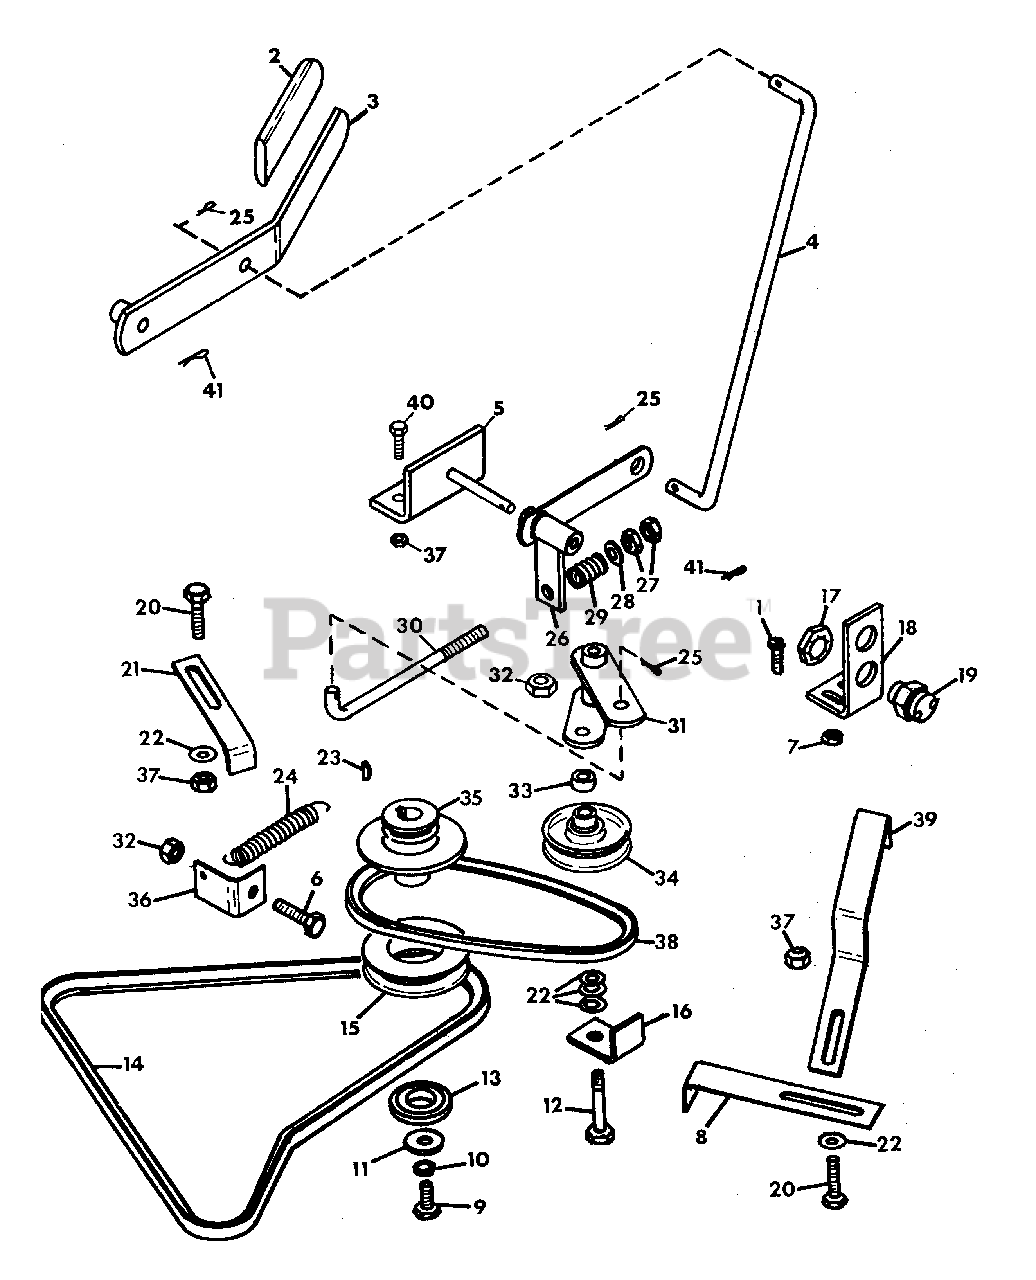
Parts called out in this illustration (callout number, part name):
1	Screw, Mach. 10-24x1.50
2	Grip, PTO Lever
3	Weldment, PTO Control Handle
4	Rod, PTO Control
5	Weldment, PTO Hand Lever Brkt.
6	Bolt, Hex 3/8-16x1.00
7	Nut, Lock 10-24
8	Belt Guide, Rear Clutch Hub
9	Bolt, Hex 7/16-20x2.00
10	Washer, Lock 7/16
11	Washer, Special Flat
12	Bolt, Hex 3/8-16x2.25
13	Bearing, Ball 1.574x3.149x.708
14	Belt, Mower
15	Sheave, Mower Clutch
16	Belt Guide, PTO Idler
17	Nut, Stamped 9/16-18
18	Bracket, Interlock Switch
19	Switch, Interlock
20	Bolt, Hex 5/16-18xl.75
21	Belt Guide, Front Clutch Hub
22	Washer, Flat .344x.688x.065
23	Key, Square .250x1.250
24	Spring, PTO Return
25	Pin, Cotter .063x1.00
26	Weldment, PTO Clutch Lever
27	Nut, Hex 3/8-16
28	Washer, Flat .406x.812x.065
29	Spring, Comp. 1.0x.78
30	Rod, PTO Clutch Actuating
31	Weldment, PTO Clutch Actuating
32	Nut, Lock 3/8-16
33	Spacer
34	Pulley
35	Weldment, Clutch Hub
36	Tab, PTO Return Spring
37	Nut, Lock 5/16-18
38	Belt, PTO Clutch
39	Belt Guide, PTO Clutch
40	Bolt, Hex 5/16-18x.75
41	Pin, Cotter .094x.625
